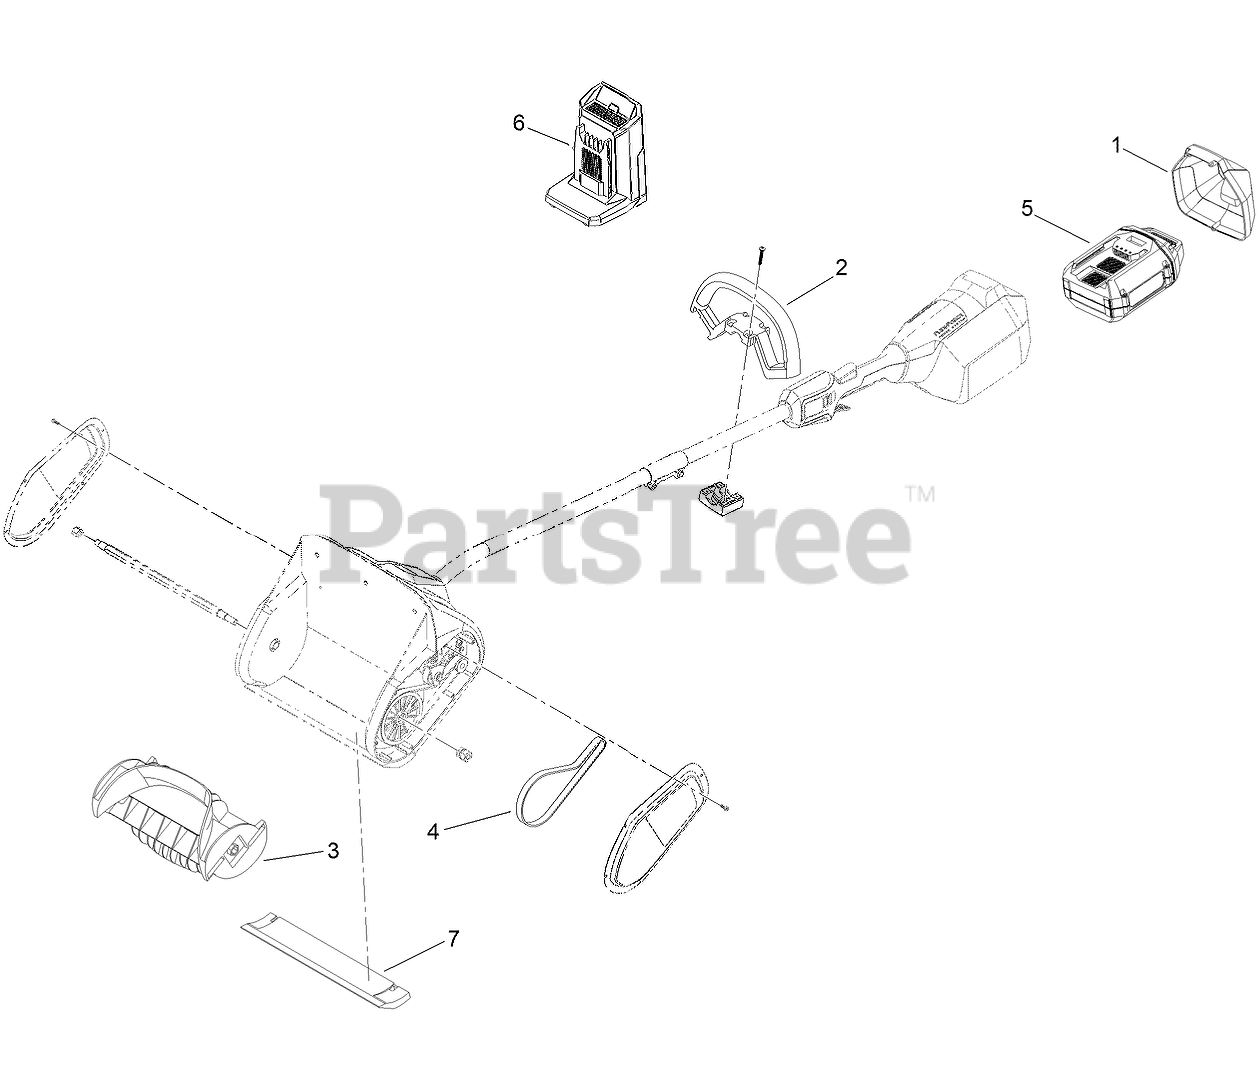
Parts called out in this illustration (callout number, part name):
1	COVER-BATTERY
2	HANDLE-TRIMMER
4	BELT-DRIVE
5	BATTERY-60V, 1P 2.5AH
6	CHARGER-60V
7	SCRAPER
